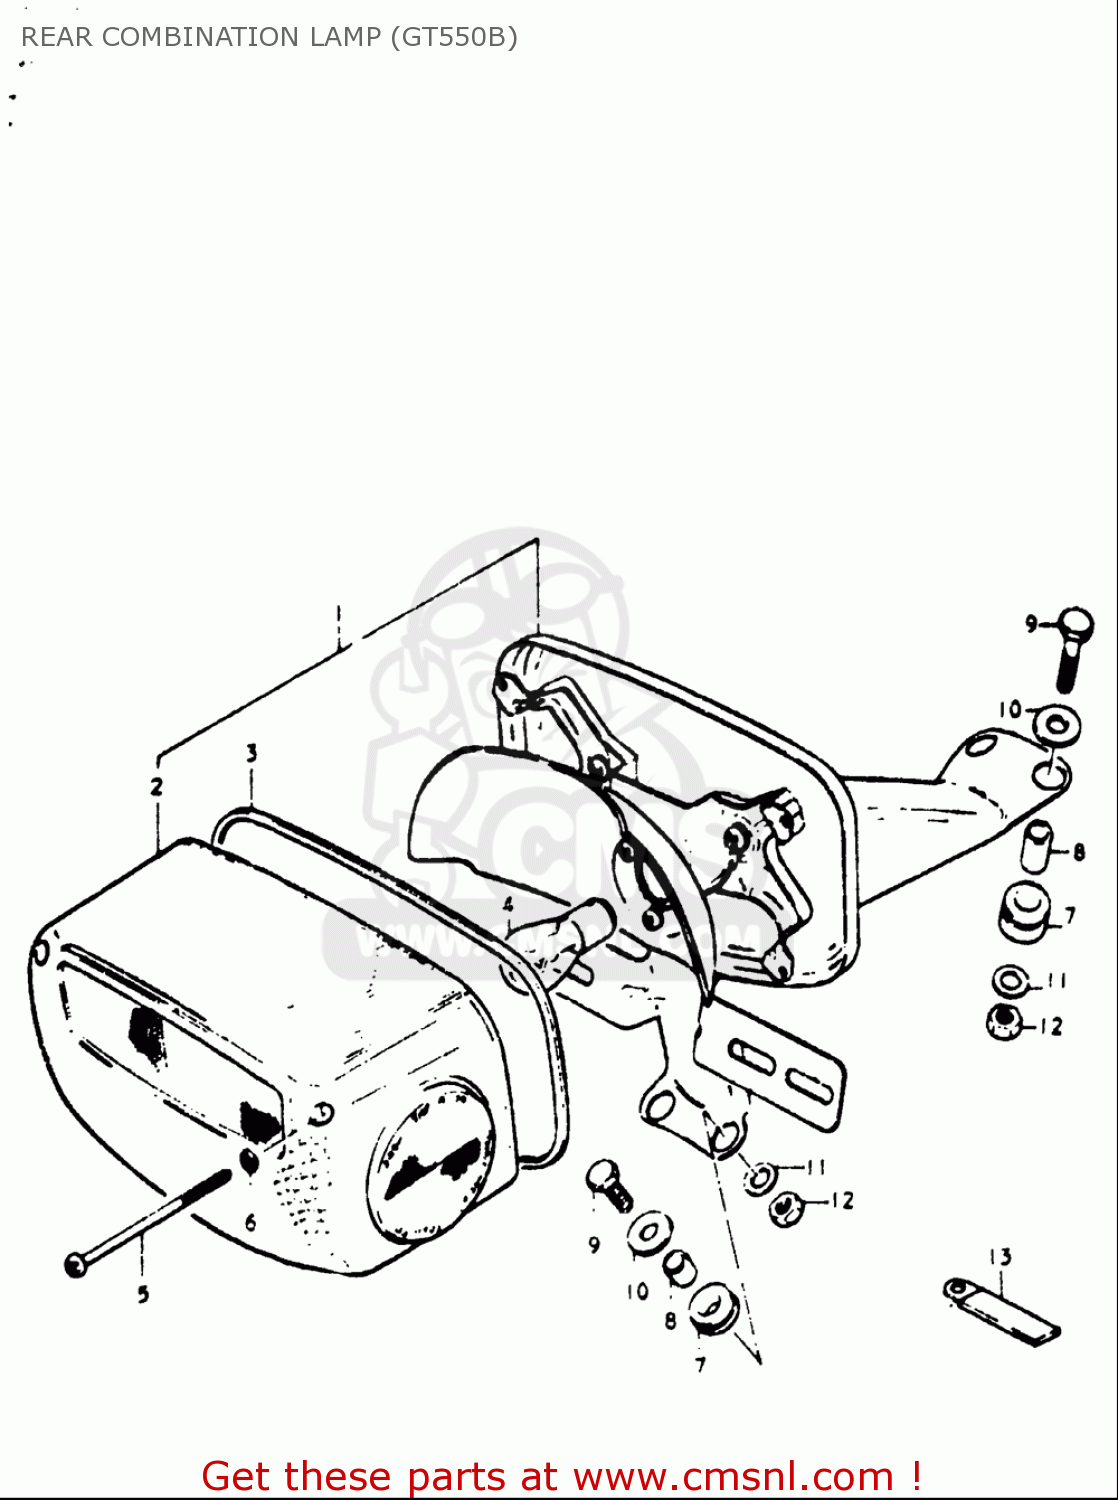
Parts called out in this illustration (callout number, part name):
2	LENS
3	GASKET (NAS)
4	BULB(12V23W)
6	GASKET (NAS)
7	CUSHION
8	SPACER
9	BOLT
10	WASHER(6.5X20X1.2)
11	WASHER
12	NUT
13	CLAMP
